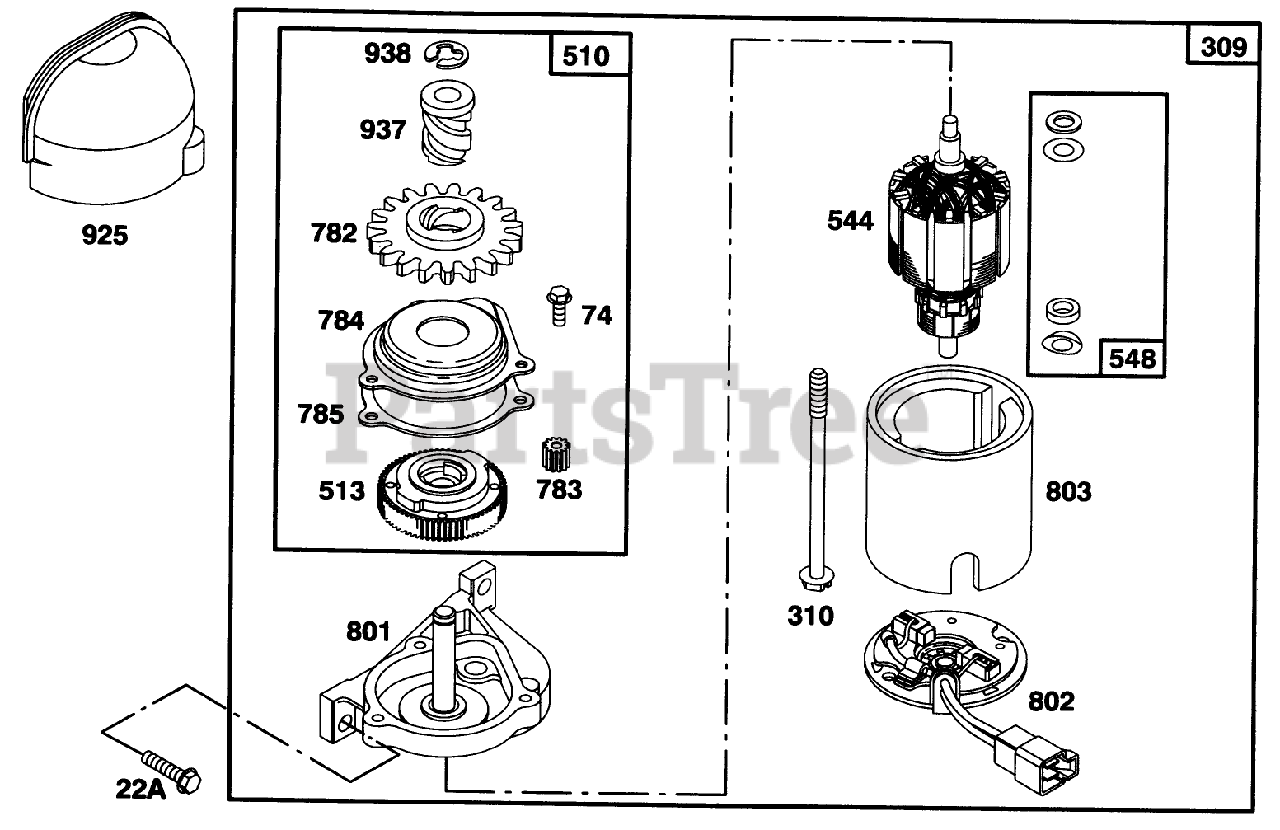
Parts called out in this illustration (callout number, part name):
22A	SCREW - CARBUERTOR MTG
74	SCREW - SEM
510	DRIVE SET
513	CLUTCH - STARTER
548	WASHER ASSEMBLY
782	GEAR - STARTER
925	COVER - STARTER
938	RETAINER - LOCK
